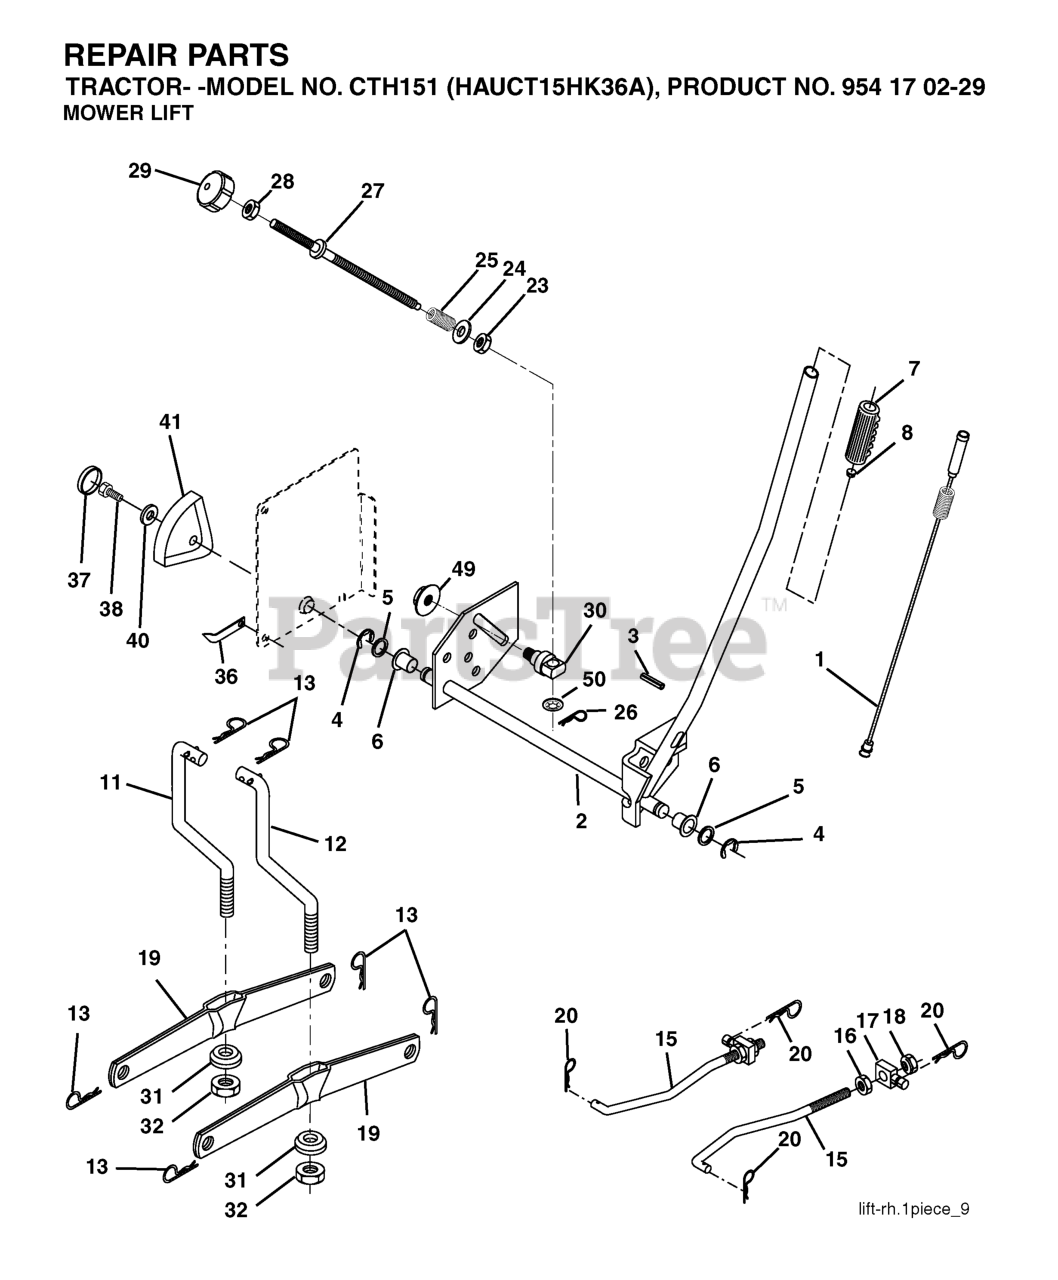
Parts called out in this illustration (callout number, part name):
1	WIRE ASM INNER W/ PLUNGER LT
2	SHAFT ASM R HANDLE
3	PIN GROOVE.
4	RETAINING RING LT
6	BEARING.NYLON
7	GRIP HANDLE
8	PLUNGER BUT KIT
11	LINK
12	LINK
13	RETAINER-SPRNG RB
15	LINK.SUSPENSION.FRONT
16	NUT.HEX.JAM.1/2-13
18	NUT.LK.W/WSH.1/2.
19	ARM.REAR.SUSPENSION
20	SPRING RETAINER
25	SPRING**
26	RETAINER CLIP
27	ROD ADJ LIFT
28	NUT
29	KNOB INF 3/8-16
31	BEARING.PIVOT.LIFT
32	NUT CROWNLOCK 3/8-24
36	POINTER, HEIGHT INDICATOR(2 2)
38	SCREW 5/16-18X1
41	HEIGHT INDICATOR
49	NUT
50	NUT PUSH M
